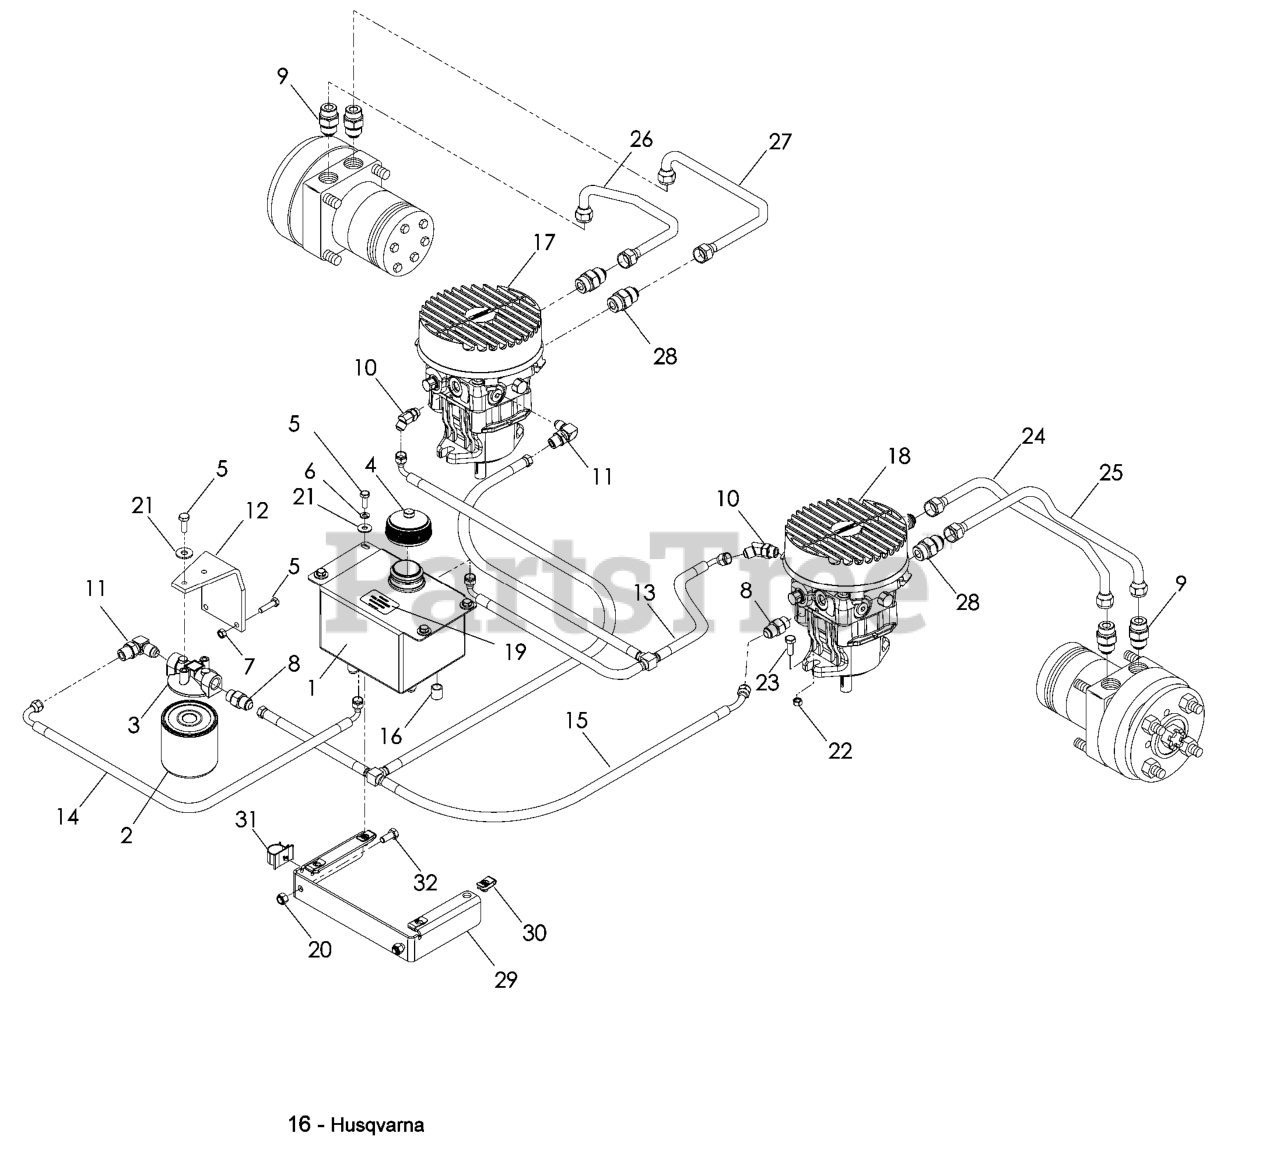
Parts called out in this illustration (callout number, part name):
2	HYDRAULIC OIL FILTER
3	FILTER HEAD
4	HYDRAULIC CAP
5	HCS 1/4C X 3/4 HCS
6	LOCKWASHER 1/4"
7	NUT.1/4-20.HEX.NYLOC.ZD
8	HYDRAULIC FITTING
10	45 DEG ADJ ELBOW
11	ELBOW, F6801-6-6-0 90 DEGREE
12	OIL FILTER BRKT
13	HOSE, T-ASM RETURN
14	HOSE, TANK - FILTER LINE
15	HOSE, T-ASM SUPPLY
16	NUT 9/16-18 JIC CAP
17	HG_PUMP, 10CC W/FAN RIGHT
18	HG_PUMP, 10CC W/FAN LEFT
19	DECAL, OIL TANK
20	NUT 5/16 NYLOC
21	WASHER 1/4 FLAT
22	NUT 3/8C CENTERBLOCK
23	4CS 3/8C X 1 SERRATED HEAD
24	HOSE, RPA - MA LINE
25	HOSE, RPB - MB LINE
26	HOSE, LPA - MB LINE
27	HOSE, LPB - MA LINE
28	FITTING, STRAIGHT F6400-8-8-0
29	TANK MOUNT
30	1/4C - U TYPE RETAINER
31	PUSH-MOUNT WIRE CLIP
32	HCS 5/16C X 3/4
